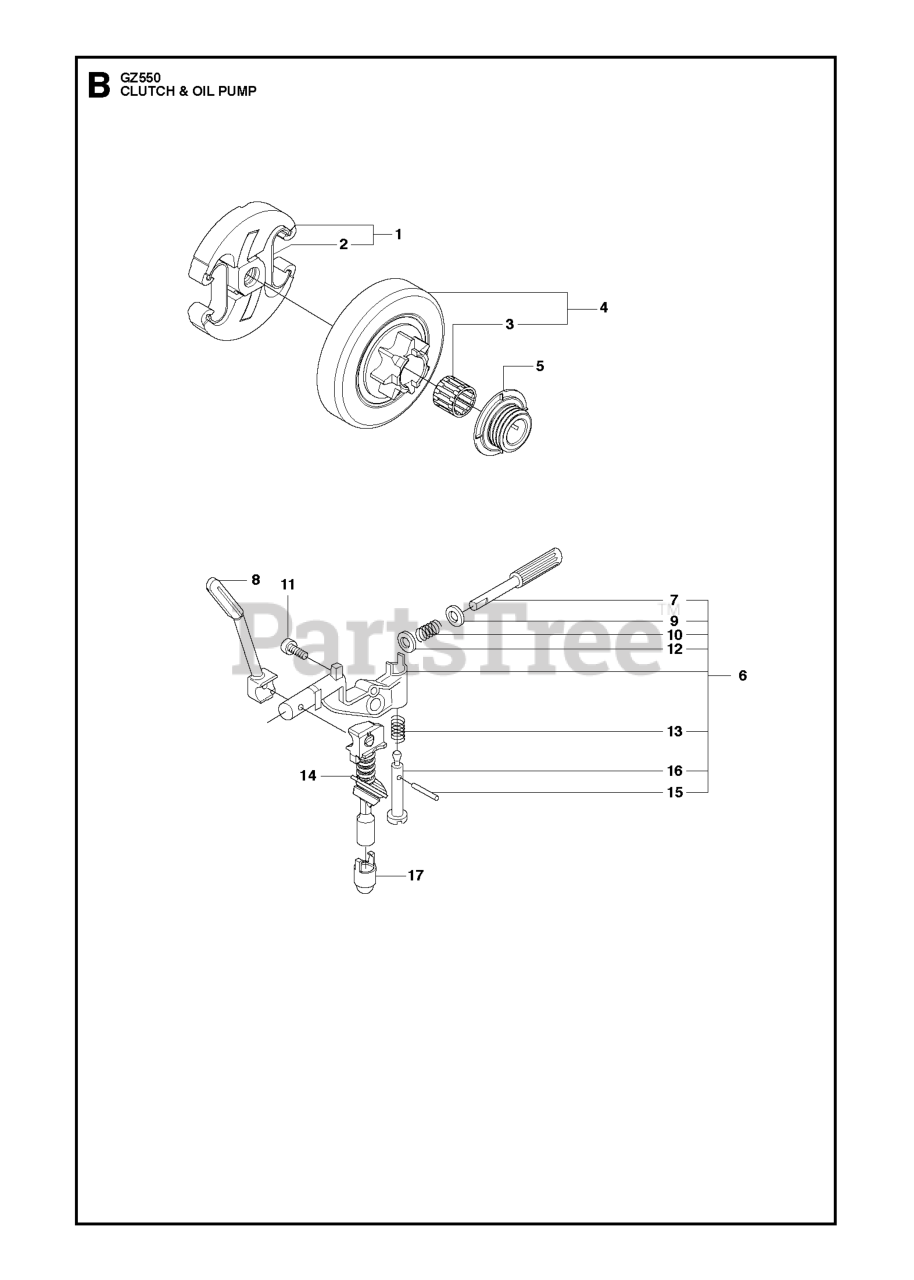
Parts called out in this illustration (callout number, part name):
1	CLUTCH ASSY
3	NEEDLE BEARING
4	CLUTCH DRUM
5	GEAR WORM OILER
6	OIL PUMP ASSY
7	PUMP PISTON
8	OIL HOSE
9	WASHER STEEL
12	WASHER STEEL
14	OIL HOSE
16	ADJUSTER
17	OIL SCREEN
